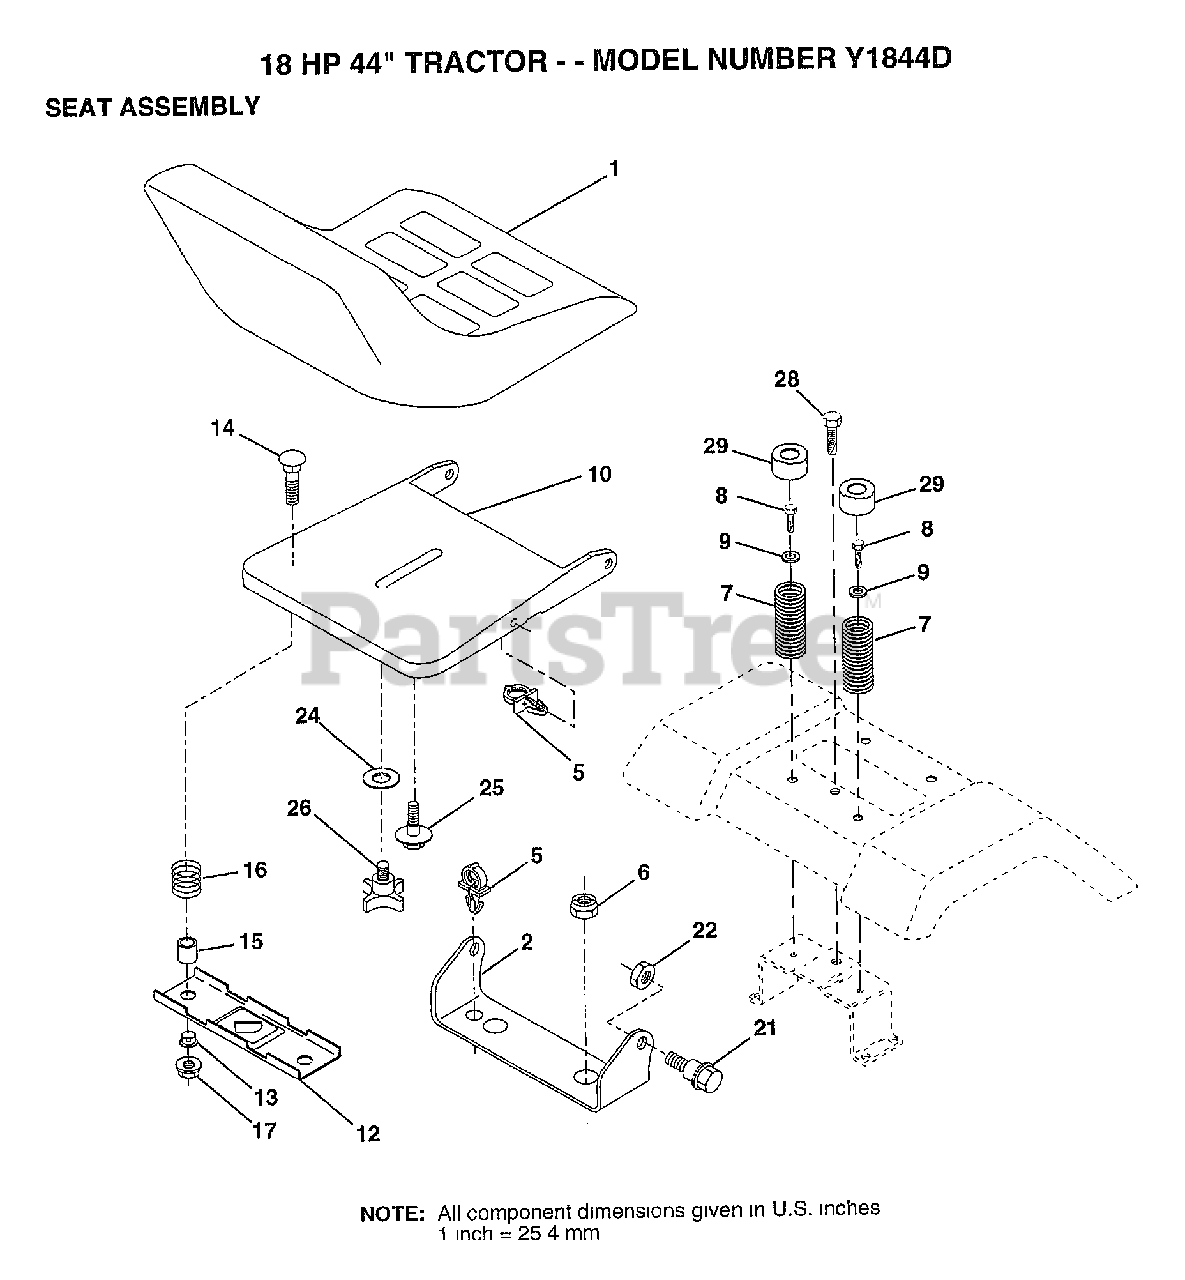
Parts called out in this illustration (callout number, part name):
2	BRACKET PVT SEAT
5	CLIP PUSH - IN
7	SPRING COMPRESSIO
8	SCREW LT
9	WASHER
12	BRKT SWITCH
13	BUSHING
15	SPACER SPLIT
16	SPRING COMPRESSED
21	BOLT.SHLD.5/16-18
24	WASHER
25	"BOLT,SHOULDER"
26	"KNOB 1/2"" YT"
28	SCREW LT
29	CAP SPRING
